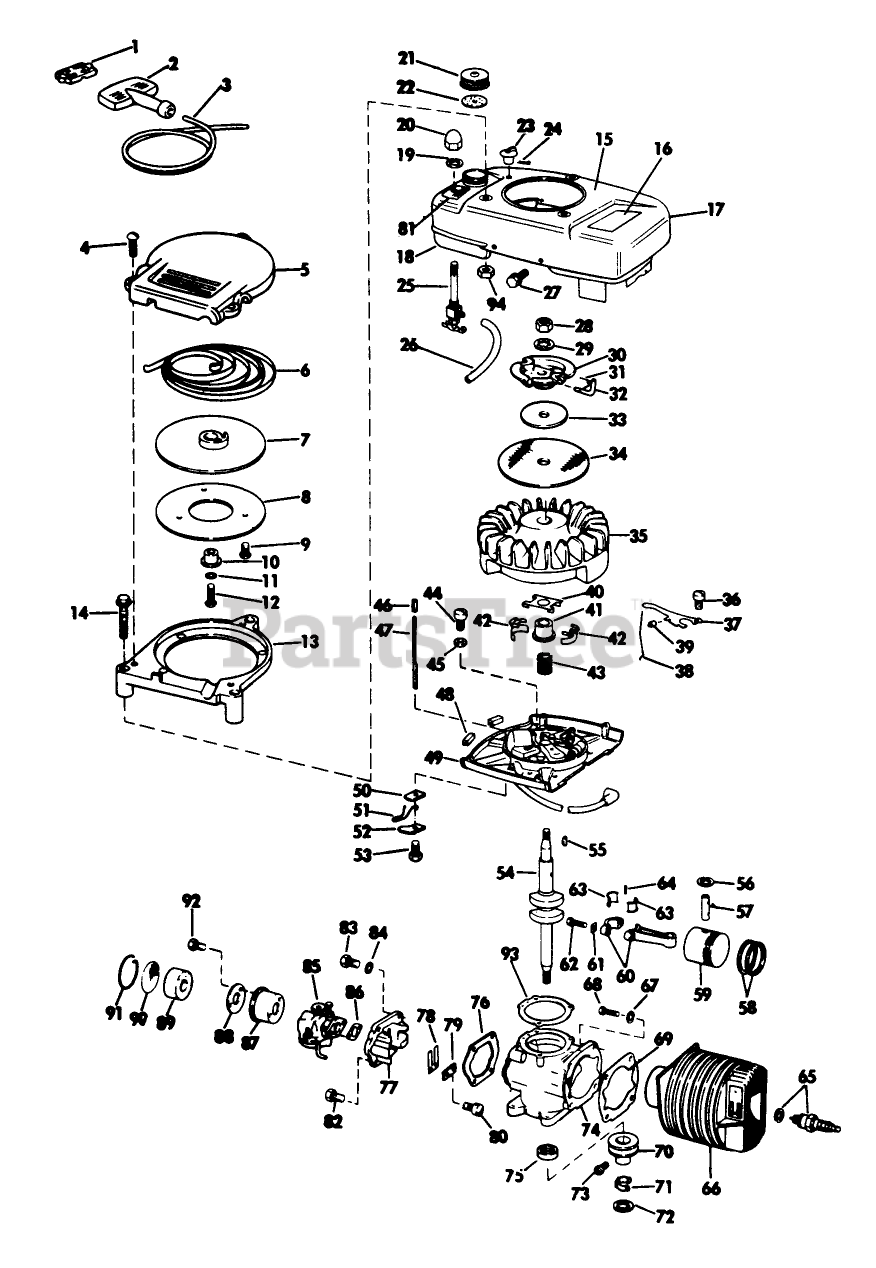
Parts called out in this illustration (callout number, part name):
6	RECOIL SPRING
8	Plate-Pulley
20	PALNUT S
23	KNOB, CHOKE BAR
24	Cotter Pin-Choke Knob
25	VALVE&SCREEN SM
27	SCREW S
32	PIN - STARTER
37	GOVERNER LEVER AY
38	GOVERNOR ROD S
39	WEAR BLOCK S
41	COLLAR S
53	Screw Shut-off Switch
54	Crankshaft
56	RING-RETAINING
63	LINER ASM
65	Spark Plug and Gasket
69	GASKET S
73	Screw-Pulley Drive
79	PLATE-BACKUP, REED
82	SCREW S
83	SCREW S
86	GASKET S
88	BACK-UP PLATE
89	ELEMENT
93	GASKET S
